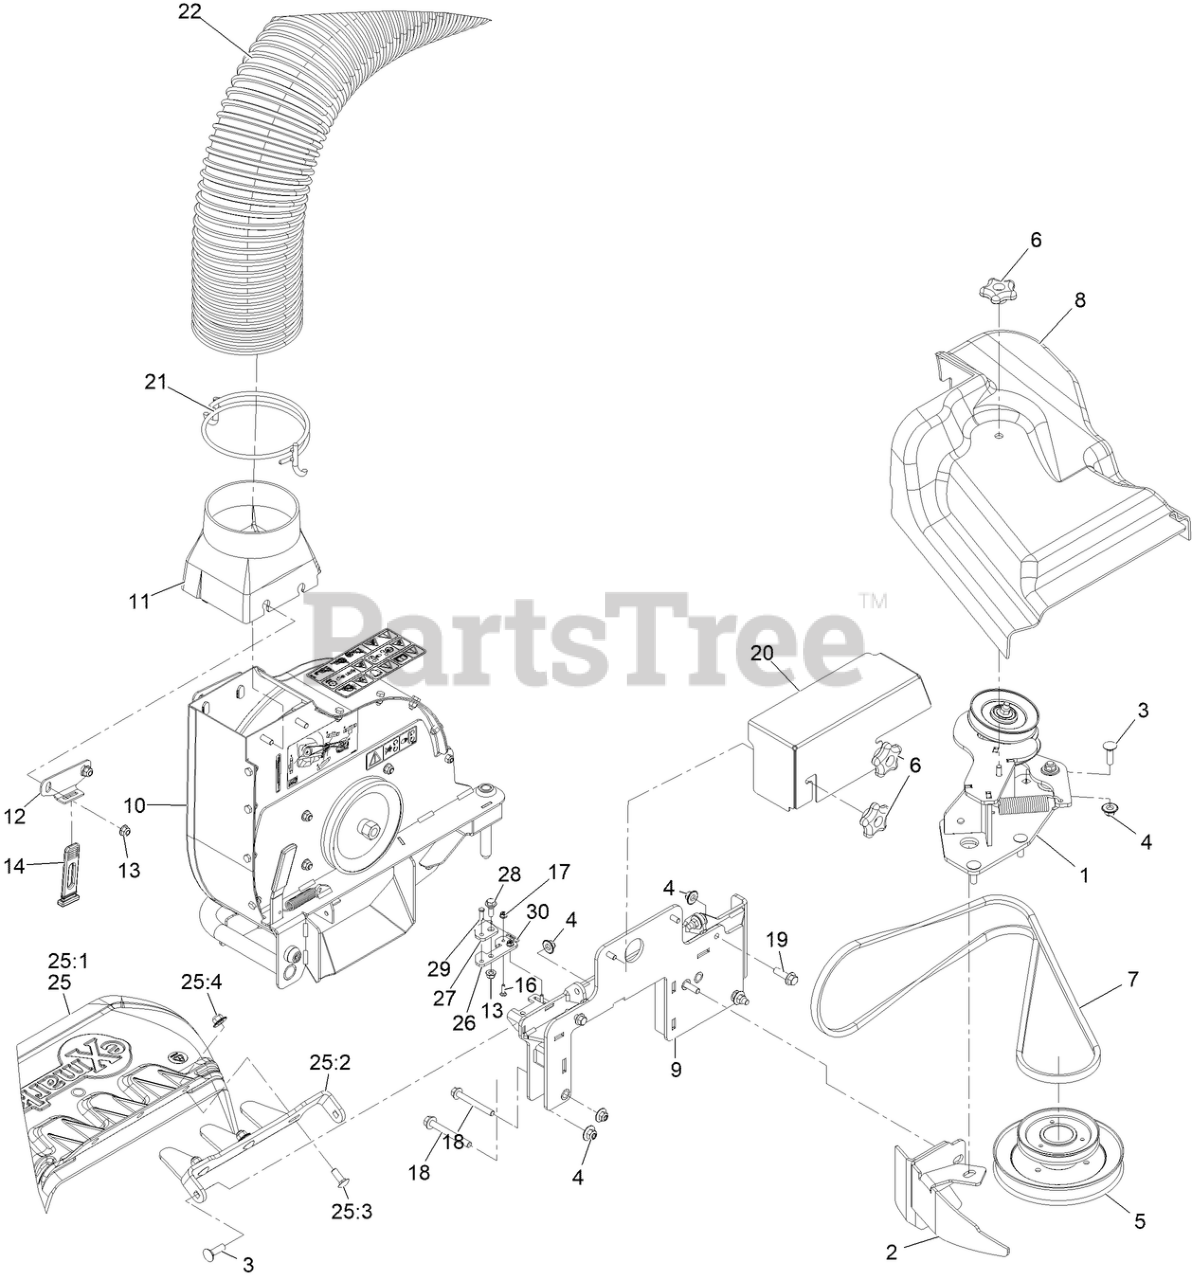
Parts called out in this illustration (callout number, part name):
1	ASM-Blower Idler
2	BAFFLE-DOGLEG
3	BOLT-CARR
4	Nut-Nyloc 3/8-16 Flg
5	JACKSHAFT,UV DRIVE 604 SPLINED
6	KNOB-HANDLE
8	Cover-Belt
9	MOUNT ASM-BLOWER
10	BLOWER ASM
11	TRANSITION
13	NUT-HF, NI
14	STRAP-DOWN, HOLD
16	SCREW-CARR
18	Screw-HHF
19	SCREW-HHF
20	Guard-Belt, Blower
21	CLAMP-HOSE, BAGGER
22	HOSE-FLEXIBLE
25	ASM,DISCHARGE CHUTE
25:1	CHUTE,DISCHARGE
25:2	BRACKET,DISCHARGE CHUTE
25:3	SCREW-CARR
25:4	Nut-Nyloc 3/8-16 Flg
26	Catch-Blower Latch
27	Lock Bar-Blower Latch
28	SCREW-SHOULDER
29	PIN-CLEVIS
